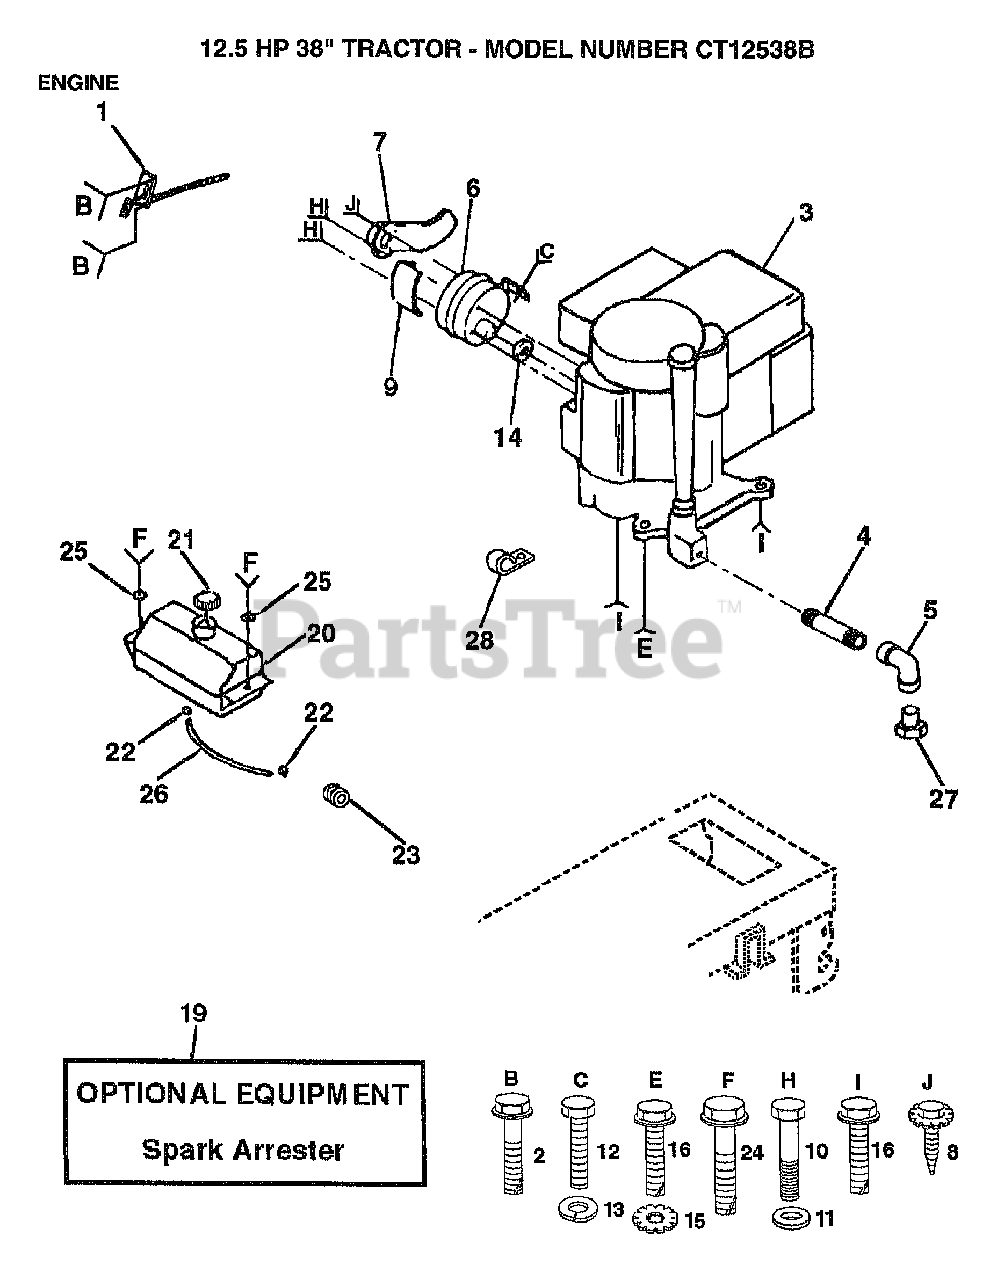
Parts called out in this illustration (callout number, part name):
1	THROTTLE CONTROL
2	SCREW LT
4	PIPE NIPPLE
5	ELBOW
6	MUFFLER LTV
7	DEFLECTOR MUFFLER
9	SHIELD HEAT LTV
10	"BOLT,HEX"
11	WASHER T
12	BOLT
13	LOCKWASHER
15	LOCKWASHER
16	SCREW
20	TANK.FUEL.LT.
22	HOSE CLAMP
24	SCREW
25	WASHER GT
26	FUEL LINE T
28	CLIP T
